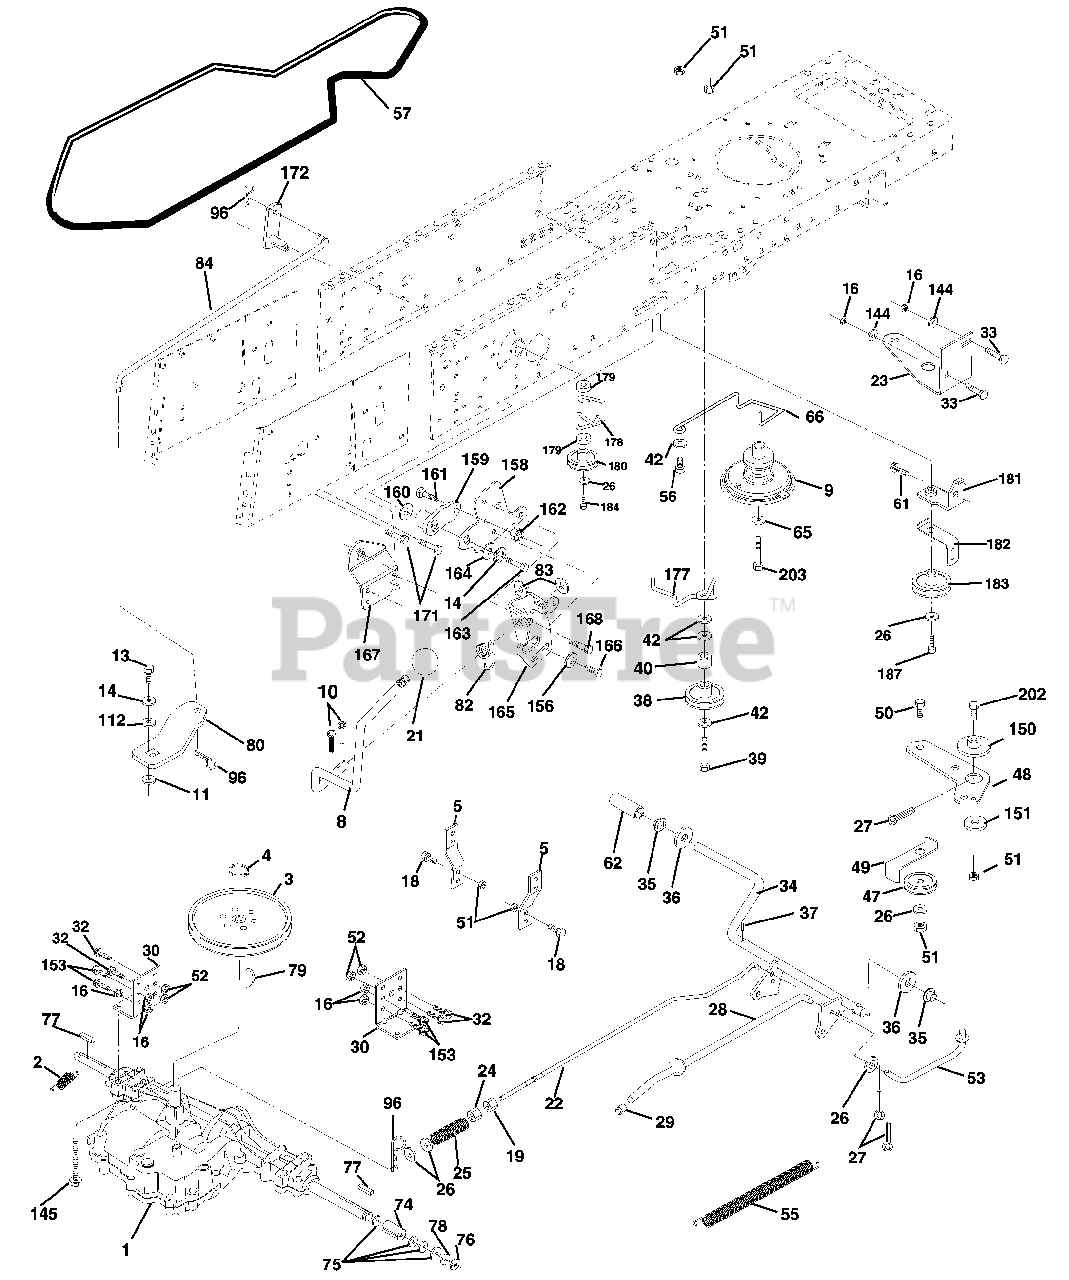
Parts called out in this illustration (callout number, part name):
2	Spring Brake Return
3	Pulley Transaxle
4	Ring Retainer #5100-62
5	Strap torque 30 degrees
8	Rod Shift Fender Adjust Lt
9	Clutch Asm Noram
10	Pin, Cotter 1/8 x 1
11	Washer Plate Shf .3888 sq hole
13	Bolt 1/4-28 Unf Gr 8 w/patch
14	Washer, Lock Hvy Helical
16	Nut, Lock Hex w/Ins 5/16-18 UNC
18	Bolt Hex 3/8-16 UNC x 1 Gr.5
19	Nut, Lock Hex w/Wsh 3/8-16 UNC
21	Knob Duckhead 1/2-13 Unc Blk
22	Rod, Brake CRD 0650
23	Bracket Clutch Noram
24	Nut
25	Spring, Rod, Brake
26	Washer 13/32 x 13/16 x 16 Ga.
27	Pin, Cotter 1/8 x 3/4
28	Rod, Parking Brake
29	Cap, Parking Brake
30	Bracket, Mfg. Transaxle
32	Bolt Hex 5/16-18 UNC x 3/4
33	Bolt Rdhd Sqnk 5/16-18 Unc x 3/4
34	Shaft, Asm Pedal Foot CRD
35	Bearing, Nylon
36	Washer 21/32 x 1 x 16 Ga.
37	Pin, Roll 3/16 x 1"
38	Pulley, Flat
39	Bolt Fin Hex 3/8-16 UNC x 2-3/4
40	Spacer, Split 395 x 59 Bzp
42	Washer 13/32 x 13/16 x 12 Ga.
47	Pulley, Idler, V Groove Plasitc
48	Bellcrank Clutch Grnd Drv
49	Retainer, Belt Style Spring
50	Bolt Hex Hd 3/8-16 UNC x 1-1/2
51	Nut, Crownlock 3/8-16 UNC
52	Nut Crownlock 5/16-18
53	Link, Clutch 7.66
55	Spring, Return, Clutch
56	Bolt, Hex 3/8-16 UNC x 1-1/4
57	V-Belt Kev PMST CRD
61	Screw 3/8-16 x 3/4
62	Cover, Pedal
65	Washer
66	Keeper, Belt Engine F-Proof
74	Spacer Axle
75	Washer 25/32 x 1-1/4 x 16 Ga.
77	Key, Square
78	Washer 25/32 x 1-5/8 x 16 Ga.
79	Key Woodruff
80	Arm Shift PMST 20" Tires
82	Spring, Torsion
83	Washer 17/32 x 3/4 x 16 Ga.
84	Link Shift CRD Pmst 18" Tires
96	Spring, Retainer 1"
112	Washer 9/32 x 3/4 x 10 Ga.
144	Washer 11/32 x 5/8 x 16 Ga.
145	Bolt Hex FGHD 5/16-18 x Gr 5
150	Bushing, Bellcrank Grnd Dr
151	Washer 13/32 x 2 x 10 Ga.
153	Bolt Hex Hd 5/16-18 Unc x 1
156	Washer Srred 5/16 ID x 1.125
158	Bracket Shift Mount
159	Hub Tapered Flange Shift Lt
160	Washer 29/32 x 1-1/4 x 16 Ga.
161	Bolt Rdhd Sqnk 1/4-20 x 3/4 Gr 5
162	Nut Crownlock 1/4-20 Unc
163	Bolt Hex Fin 1/4-20 Unc x 1 Gr 5
164	Washer 5/8 x .281 x 10 Ga.
165	Bracket Pivot Lever
166	Screw 5/16-18 x 5/8
167	Bracket Support Shift CRD
168	Bolt Shoulder 5/16-18 x .561
171	Screw Thdrol 3/8-16 x 1/2 Ty-Tt
172	Shaft Asm Shift Front CRD PMST
177	Keeper Flat Idler 3.06" CRD
178	Keeper Belt Idler 1.88" CRD
179	Washer Sintered
180	Pulley Flat Composite 3.06"
181	Bracket Idler Ground Drive CRD
182	Keeper Belt 2.5" Od V-Idler CRD
183	Pulley V-Idler 2.50" Od CRD
184	Screw Hexwsh Thdrol 3/8-16 x 2-3/4
187	Screw Thdrol 3/8-16 x 1-1/4
202	Bolt Carr Sh 3/8-16 x 1/2 Ty-Tt
203	Bolt Hex 7/16-20 x 5
